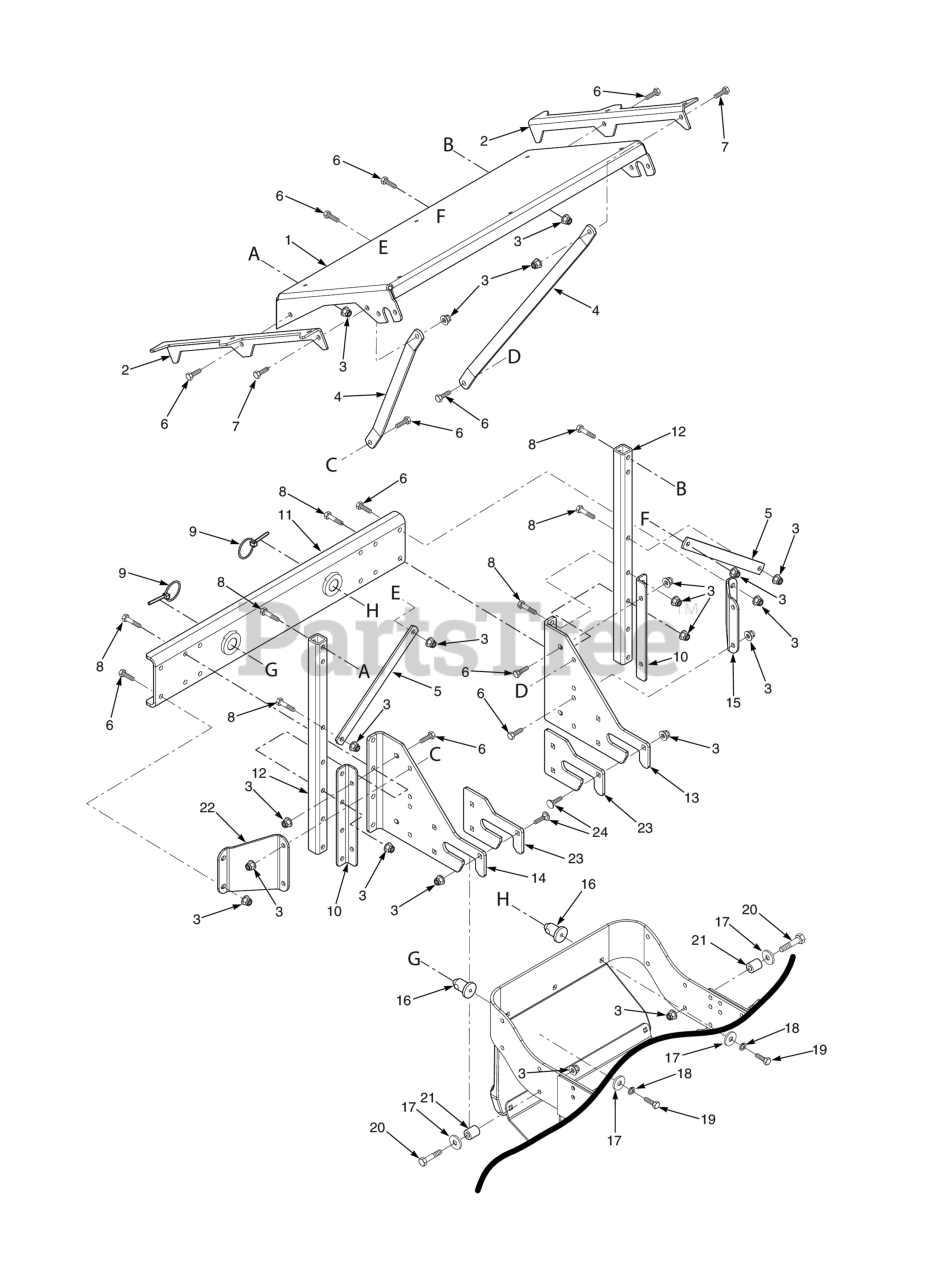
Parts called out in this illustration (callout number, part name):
1	Support Frame, Hopper
2	Bracket, Hopper Support
3	Nut, Flange Elastic Stop Nut, 3/8-16
4	Brace, Stiffener
5	Brace, Engine Mounting
6	Bolt, Hex Head, 3/8-16 x 1 Gr. 5
7	Bolt, Hex Head 3/8-16 x 1-1/4" Grade 8
8	Bolt, Hex Head 3/8-16 x 2-1/4" - 61"
9	Quick Pin, 5/16" Dia.
10	Mounting Bracket, Tube
11	Mounting Bracket Weldment
12	Tube, Upright
13	Mounting Bracket, GC R.H.
14	Mounting Bracket, GC L.H.
15	Angle Bracket, GC
16	Pin, GC Locator
17	Flatwasher, 3/8-.406 x 1-1-1/2 x 7 Gauge
18	Lockwasher, 3/8" Spring, Kawasaki FX / FT & FT-EFI / B&S 32BV
19	Bolt, Hex Head 3/8-16 x 1-1/4" Grade 8
20	Bolt, Hex Head 3/8-16 x 2-1/4" - 61"
21	Spacer
22	Angle Bracket, GC
23	Wear Plate, GC
24	Carriage Bolt, 3/8-16 x 1-1/4"
